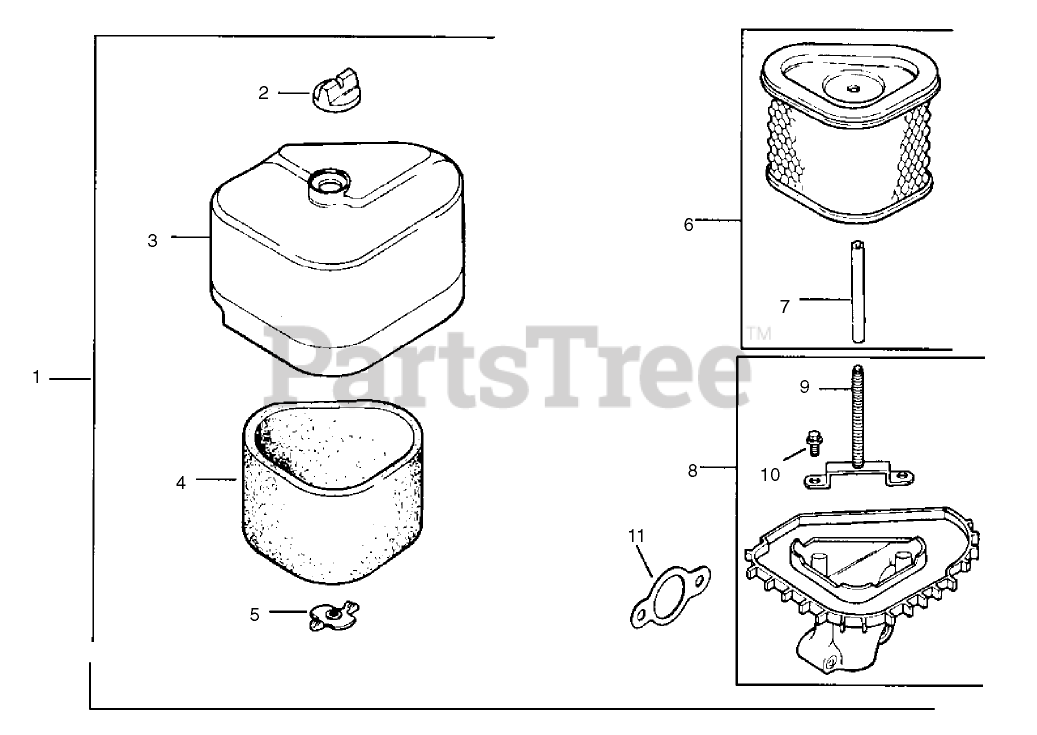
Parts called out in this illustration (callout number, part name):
1	Kit-Air Cleaner (Incl. Ref.# 2-11)
2	Knob-Cover
3	Cover-Air Cleaner
4	Precleaner-Element
5	Wingnut
6	Element-Air Cleaner (Incl. Ref.#7)
7	Seal
8	Base-Air Cleaner (Incl. Ref.#9, 10)
9	Stud-Mounting Plate
10	Screw
11	Gasket-Air Cleaner
